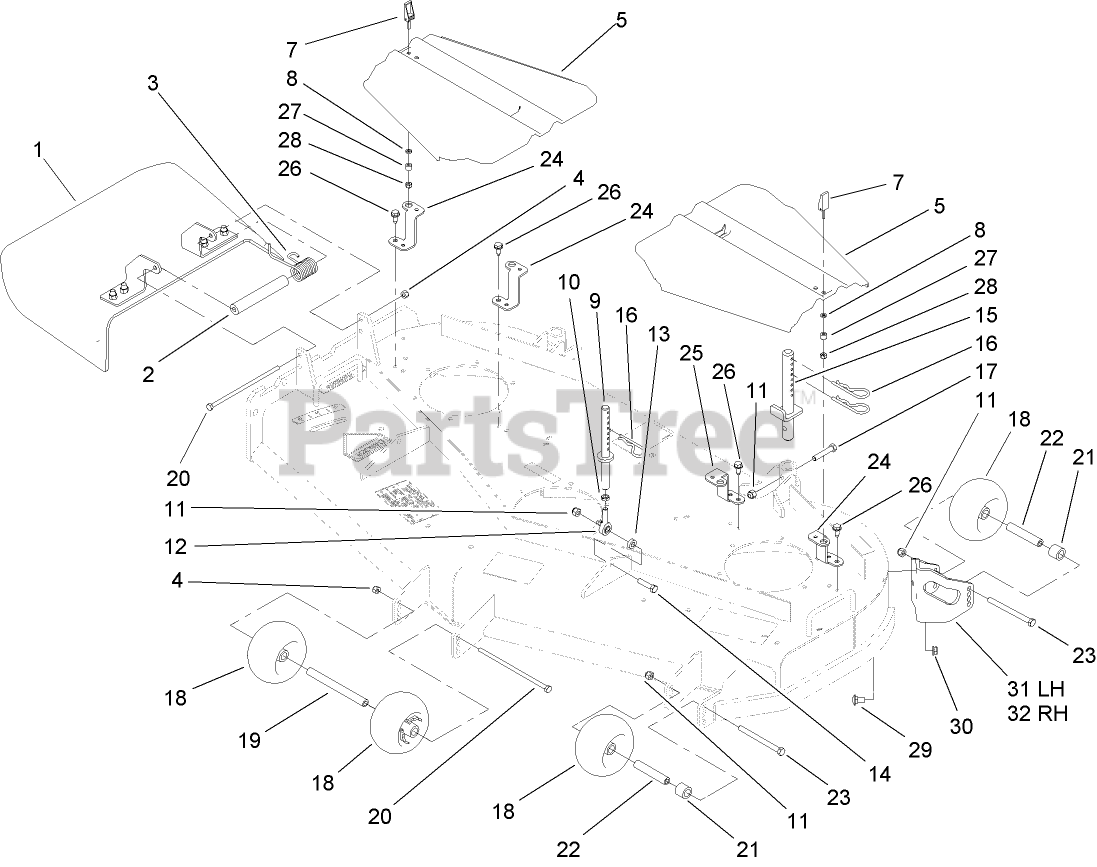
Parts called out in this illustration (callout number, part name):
1	DEFLECTOR ASM
2	SPACER
3	SPRING-TORSION
4	NUT-LOCK, NI
5	COVER-BELT
7	HANDLE-LATCH, SWELL
8	WASHER
9	FRONT PIN ASM
10	NUT-HJ
11	NUT-LOCK, NI
12	BALLJOINT
13	SPACER
14	SCREW-HH
15	REAR PIN ASM
16	PIN-HAIR
17	SCREW-HH
18	ROLLER-SCALP, ANTI
19	SPACER-WHEEL
20	SCREW-HH
21	TUBE-SPACER
22	TUBE-SPANNER
23	SCREW-HH
24	BRACKET-COVER
25	BRACKET-COVER
26	SCREW-HWHTF
27	BUSHING-LATCH, SWELL
28	NUT-LOCK, HH
29	SCREW-CARR
30	NUT-HF
31	BRACKET-ROLLER, LH
32	BRACKET-ROLLER, RH
